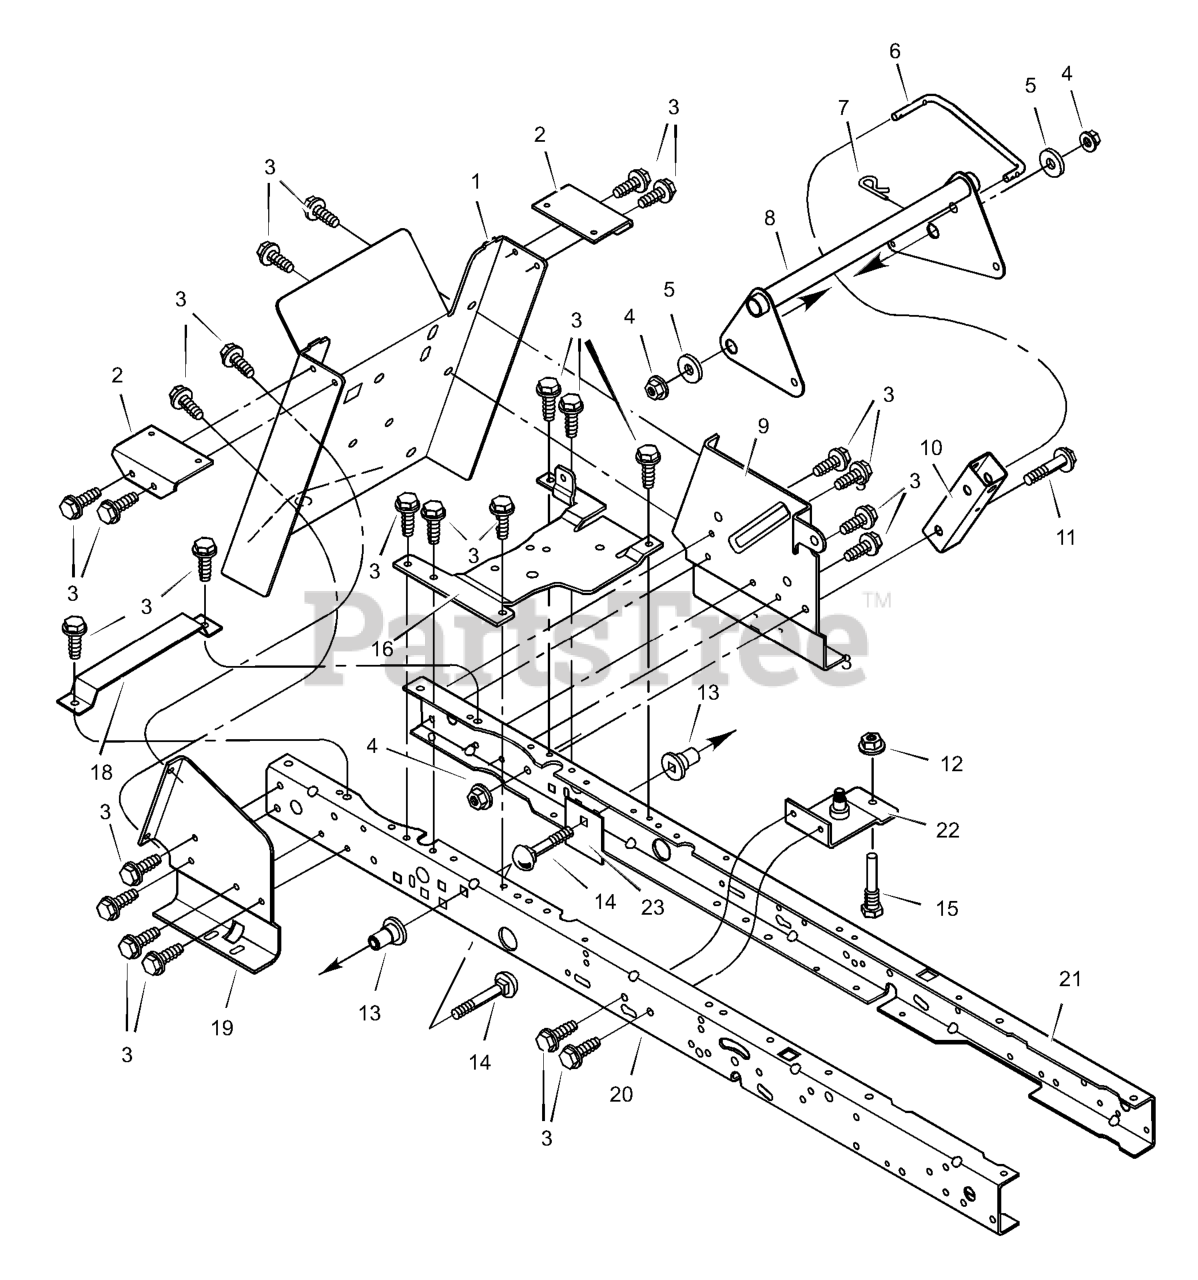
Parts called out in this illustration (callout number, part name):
1	Frame, Rear Hitch
2	Bracket, Seat Deck
4	Nut, Flange
6	Link, Lift Handle
7	Pin, Hair
8	Assembly, Lifter
9	Bracket, Left Transaxle
10	Bracket, Lift Pivot
11	Bolt, Shoulder
12	Nut
13	Spacer, Lifter
14	Bolt, Carriage
15	Guide, Belt
16	Bracket, Stationary Idler
19	Bracket, Right Transaxle
20	Frame, Right
21	Frame, Left
22	Bracket, Idler
23	Plate, Stiffening
